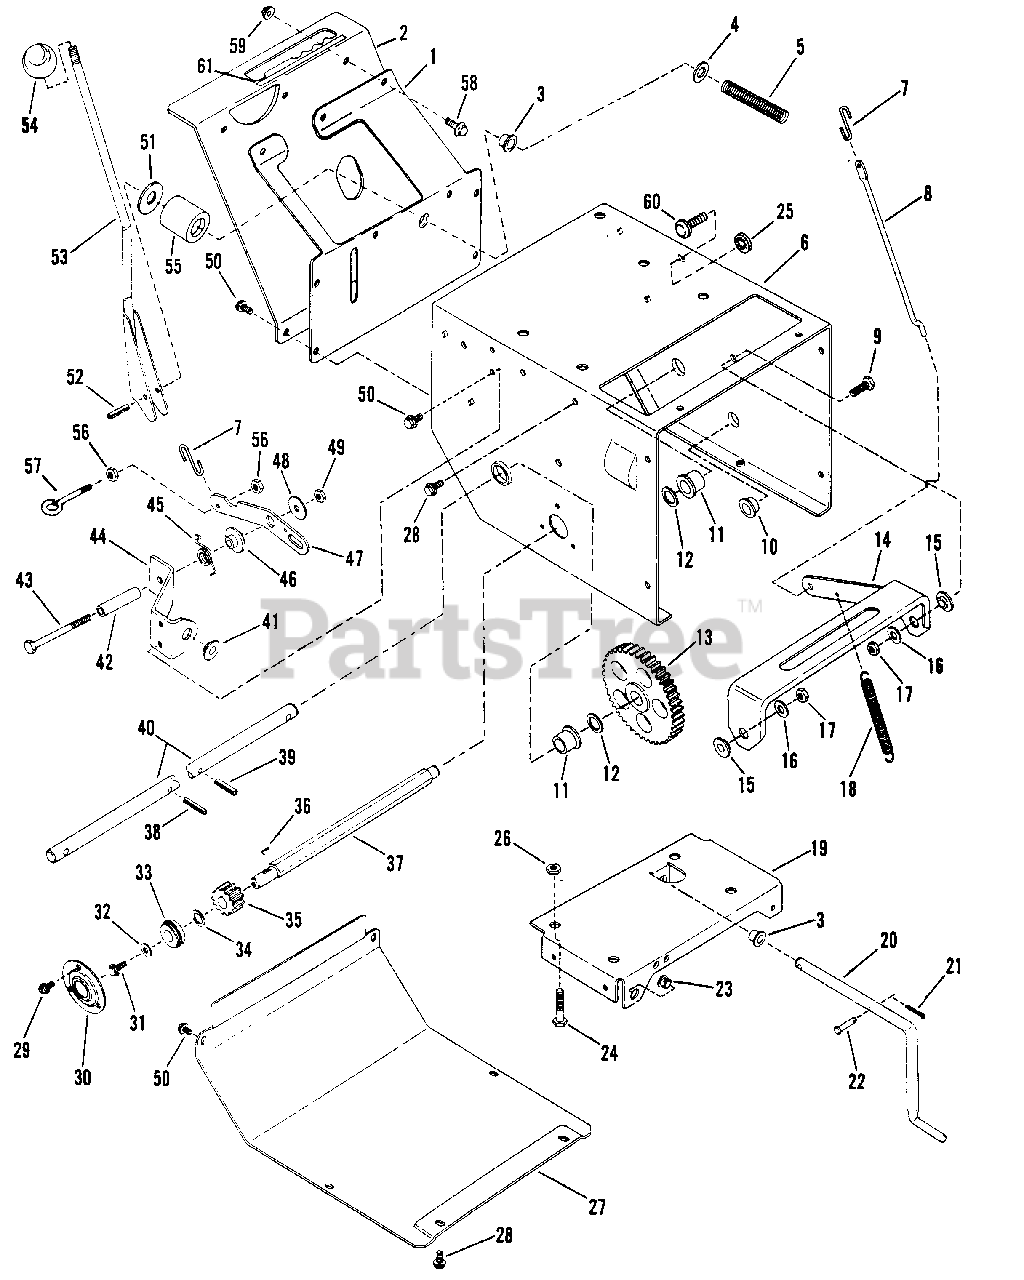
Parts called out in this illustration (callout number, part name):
2	DENTENT, Shift (7 HP Models) (Shown)
3	BEARING
4	WASHER, 1/2 SAE
5	SPRING, Shift
7	"S" HOOK
8	ROD, Clutch
9	CAPSCREW, 3/8-16x1"
10	BEARING
11	BUSHING
12	WASHER
13	GEAR, Axle Shaft
14	BRACKET, Clutch
15	BUSHING
16	WASHER, 3/8 SAE
17	LOCKNUT, 3/8-16 Hex
18	SPRING, Clutch
19	SUPPORT, Engine
20	ROD, Shift (4 & 5 HP Models)
21	COTTER-PIN, 1/16x1/2"
22	PIN, Clevis
23	BUSHING
24	SCREW, 5/16-18x1" Hex Head Cap
25	RETAINER
26	NUT, 5/16-18 Hex Flange Lock
27	COVER, Frame Bottom
28	SCREW, 5/16-18x1/2" H.W.H., Self-Tapping
29	SCREW, #10x1/4" Self-Tapping
30	RETAINER, Bearing
31	SCREW, 1/4-20x1/2" Self-Tapping Hex Hd.
32	WASHER
33	BEARING, Ball
34	WASHER, Shim
35	GEAR, Pinion
36	KEY, Woodruff, 3/32x1/2"
37	SHAFT, Hex
38	PIN, 1/4 x 1-1/2" Roll
39	ROLL-PIN, 1/4-1"
40	AXLE, Shaft
41	BUSHING
43	CAPSCREW, 5/16-18x3"
44	BRACKET
45	SPRING
46	BUSHING
47	LEVER
48	WASHER, 5/16" x 1-1/4" x 3/32" Flat
49	NUT, 5/16-18 Hex Center Lock
50	SCREW, 1/4-20x3/8" Self-Tapping
51	WASHER, Thrust (4 & 5 HP Models)
52	ROLL-PIN, 3/16x1"
53	SHIFTER (4 & 5 HP Models)
54	KNOB, Shifter
55	SPACER (7 HP Models)
56	NUT, 1/4-20 Hex Flange Lock (7 HP ONLY)
57	EYE-BOLT (7 HP ONLY)
58	SCREW, 1/4-20x1/2" Hex Head Cap
59	NUT, 1/4-20 Hex Center Lock
60	BOLT, 5/16-18x5/8" Carriage
61	DECAL, Direction Control
